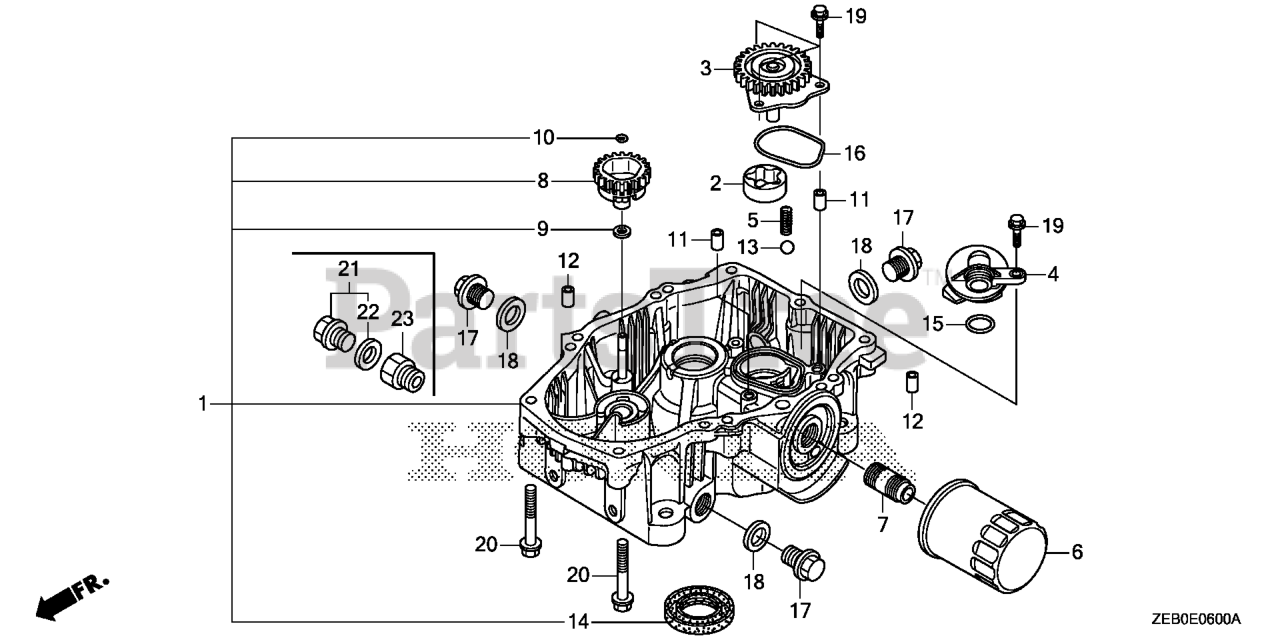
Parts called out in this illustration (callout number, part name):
1	PAN ASSY., OIL
2	ROTOR, OIL PUMP (OUTER)
3	GEAR, OIL PUMP
4	STRAINER, OIL
5	SPRING, RELIEF VALVE
6	FILTER, OIL
7	HOLDER, OIL FILTER
8	HOLDER, GOVERNOR WEIGHT
9	WASHER (6X16)
10	CLIP, GOVERNOR HOLDER
11	PIN, DOWEL (8X10)
12	PIN, DOWEL (8X14)
13	BALL, STEEL (#15) (15/32)
14	OIL SEAL (38X58X9)
15	O-RING (14.8X2.4)
16	O-RING, OIL PUMP
17	BOLT, DRAIN PLUG (20MM)
18	WASHER, DRAIN PLUG (20MM)
19	BOLT, FLANGE (6X20)
20	BOLT, FLANGE (8X45)
